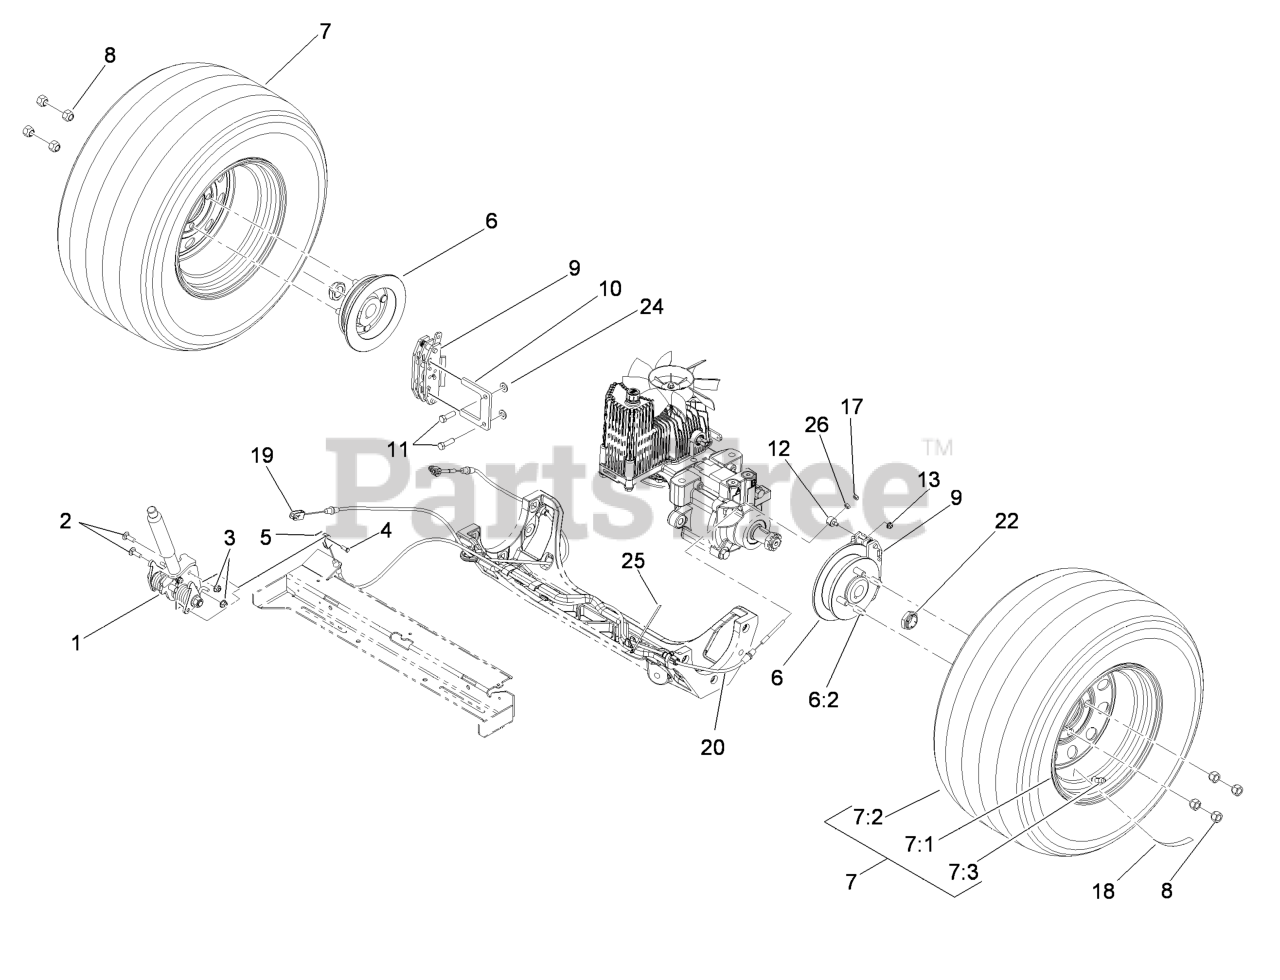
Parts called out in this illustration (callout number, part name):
1	BRAKE HANDLE ASM
2	BOLT-CARR
3	NUT-HF, NI
4	PIN-CLEVIS
5	PIN-COTTER
6	WHEEL HUB ASM
6:2	STUD-WHEEL
7	WHEEL AND TIRE ASM
7:3	Stem-Valve
8	NUT-LUG
9	CALIPER-BRAKE
10	PLATE-MOUNT, BRAKE
11	SCREW-LOCK, PATCH
17	NUT-LOCK, NI
22	LOCKNUT
24	WASHER-FLAT
25	TIE-CABLE
26	NUT-HEX
